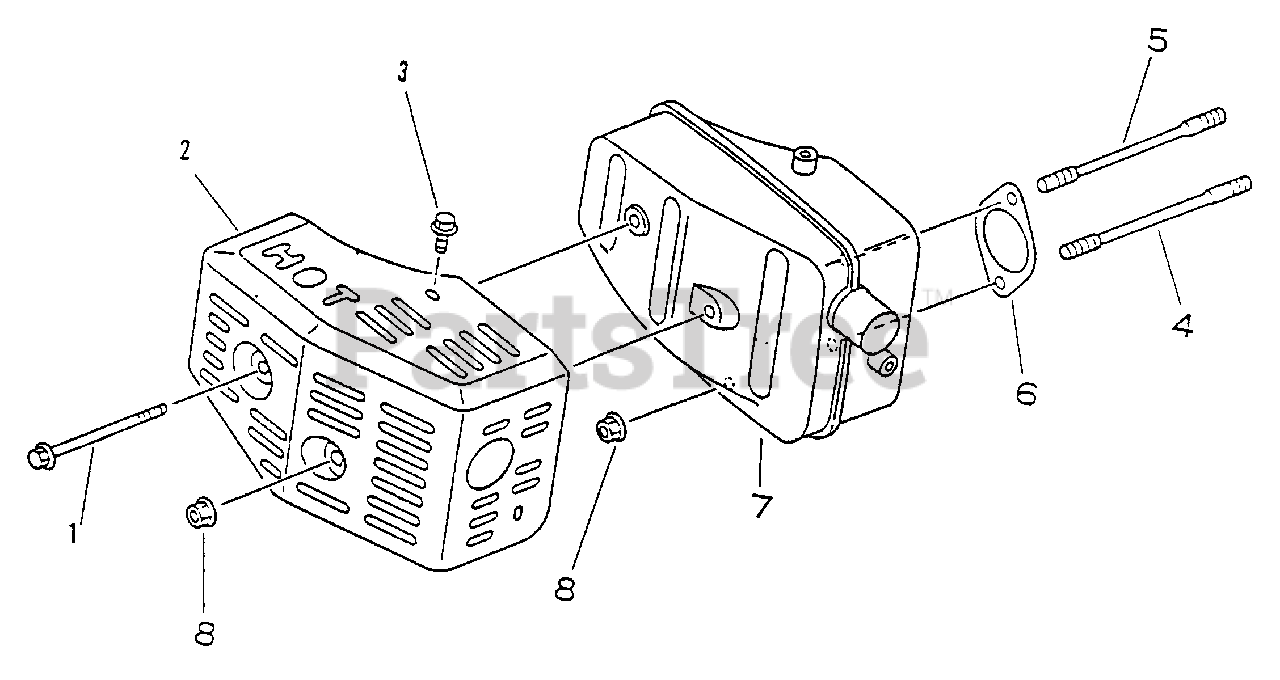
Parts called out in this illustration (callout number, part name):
1	BOLT - 6X80
2	COVER, MUFFLER
3	SCREW - 6X10
5	STUD
6	GASKET, EXHAUST
7	MUFFLER
8	NUT - 8 -- FLANGE
